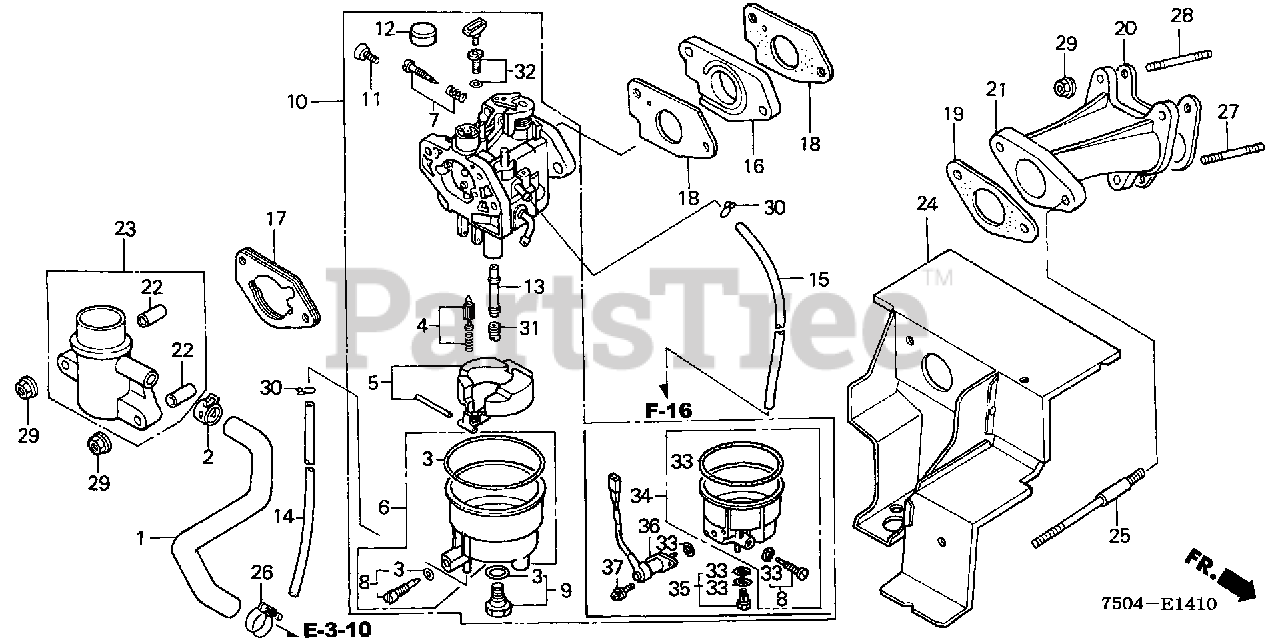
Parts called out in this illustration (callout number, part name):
1	TUBE, BREATHER
2	CLIP, BREATHER TUBE
3	GASKET SET
4	VALVE SET, FLOAT
6	CHAMBER SET, FLOAT
7	SCREW SET, PILOT
8	SCREW SET, DRAIN
9	SCREW SET
10	CARBURETOR ASSY.
11	SCREW, THROTTLE STOP
12	CAP, CHOKE LEVER DUST
13	NOZZLE, MAIN (NOT AVAILABLE)
13	NOZZLE, MAIN
14	TUBE, FUEL DRAIN
15	TUBE, AIR VENT
16	INSULATOR, CARBURETOR
17	SPACER, CARBURETOR
18	GASKET, CARBURETOR
19	GASKET, INSULATOR
20	GASKET, IN. MANIFOLD
21	MANIFOLD, IN.
22	COLLAR, AIR CLEANER
23	ELBOW SET, AIR CLEANER
23	ELBOW, AIR CLEANER
24	COVER, EX.
25	BOLT, STUD (8X123) (NOT AVAILABLE)
26	CLIP A18, TUBE
27	BOLT, STUD (6X32)
28	BOLT, STUD (6X28)
29	NUT, FLANGE (6MM)
30	CLIP, TUBE (B8)
31	JET, MAIN (#88) Use from Engine SN BE27C A.
31	JET, MAIN (#90) Use from Engine SN BE27C A.
31	JET, MAIN (#92)
31	JET, MAIN (#88)
31	JET, MAIN (#88) Use from Engine SN BE27A B to BE27A E.
31	JET, MAIN (#90) Use up to Engine SN BE27A E.
32	JET SET, PILOT (#45)
33	GASKET SET (NOT AVAILABLE)
34	CHAMBER SET, FLOAT
35	SCREW SET
36	VALVE ASSY., SOLENOID
37	SCREW-WASHER (5X12)
